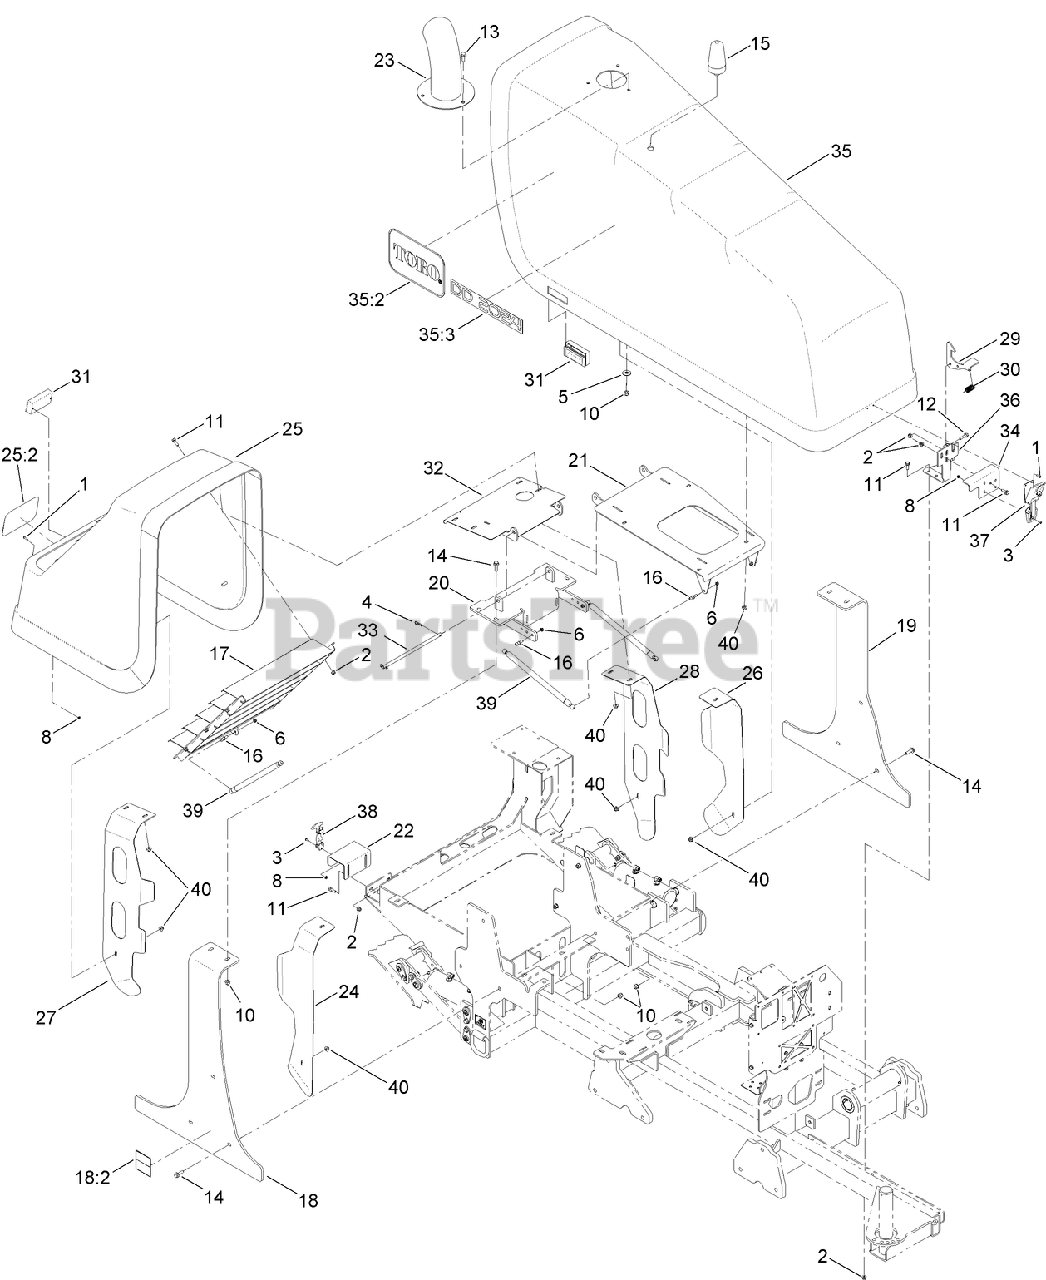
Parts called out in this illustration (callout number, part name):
1	SCREW-HSBH
2	NUT-LOCK, HHF
3	SCREW-HSBH
4	PIN-HAIR
5	WASHER-FLAT
6	NUT-LOCK, NI
8	NUT-KEPS
10	NUT-LOCK, NI
11	SCREW-HHF
12	SCREW-HHF
13	SCREW-HHF
14	SCREW-HHF
15	LIGHT-STROBE
16	STUD-BALL
18	HOOD MOUNT ASM
18:2	DECAL-WARNING, CRUSHING
19	PLATE-MOUNT, HOOD
20	SUPPORT-SHROUD
21	MOUNT-FRONT, HOOD
22	PLATE-REAR, HOOD STOP
23	EXHAUST-STACK
24	PLATE-GUIDE
25	REAR HOOD ASM
25:2	DECAL
26	PLATE-GUIDE
27	PLATE-GUIDE
28	PLATE-GUIDE
29	HOOK-HOOD, SAFETY LATCH
30	SPRING-TENSION
31	HANDLE-PULL, FLUSH
32	HINGE-REAR, HOOD
33	ROD-HINGE, HOOD
34	STOP-FRONT, HOOD
35	FRONT HOOD ASM
36	LATCH-SAFETY, HOOD
37	LATCH-DRAW, LOCKABLE
38	LATCH-FLEX, DRAW
39	SPRING-GAS
40	NUT-HF, NI
